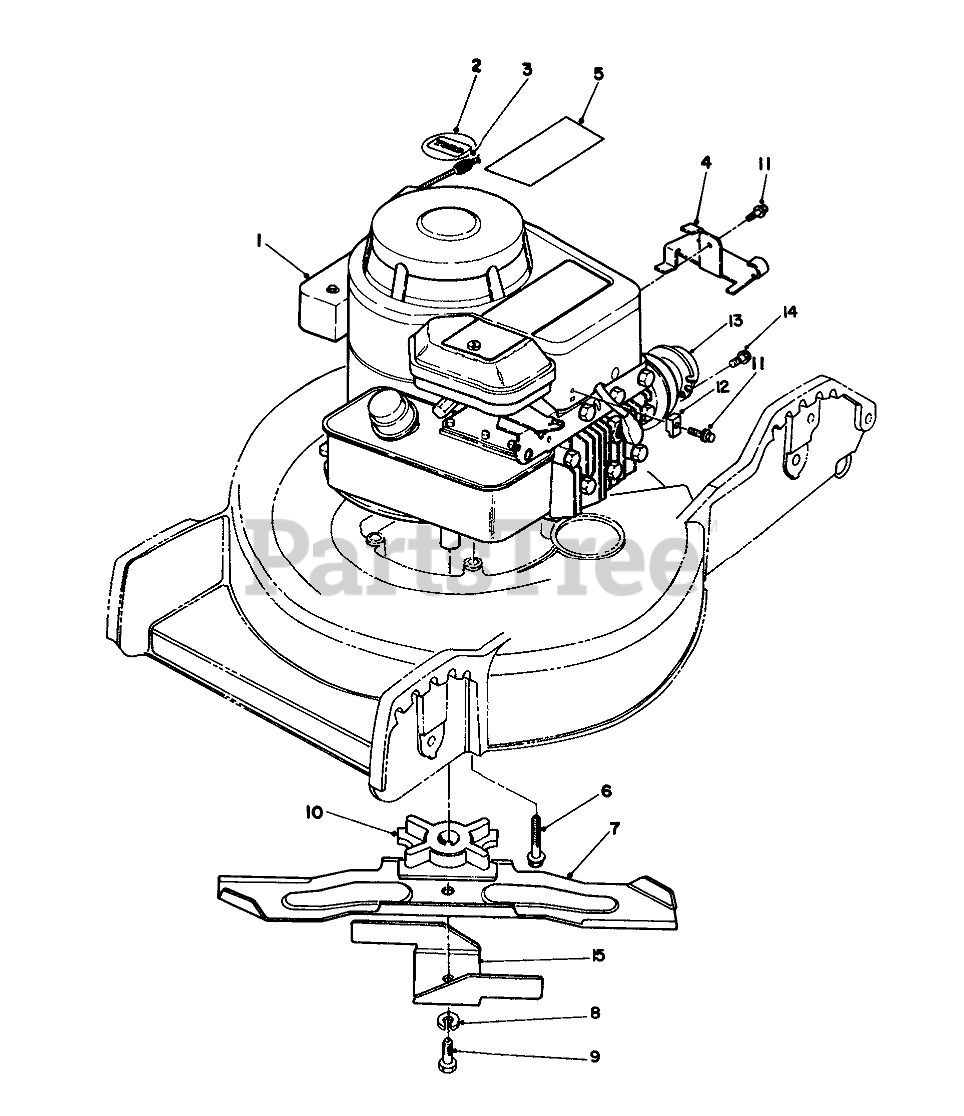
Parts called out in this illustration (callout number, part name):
2	Decal-Toro
3	STOP-ROPE
4	CABLE BRACKET
5	Decal-Engine
6	3/8-16X2 TAPTITE HEX HD
7	Blade-18"
8	WASHER-LOCK
9	SCREW-HH
10	BLADE RETAINER
11	CLAMP SCREW F/W ENGINE
12	CASING CLAMP F/W ENGINE
13	MUFFLER DEFLECTOR F/W
14	SCREW W/ENGINE
15	18 ACCELERATOR
